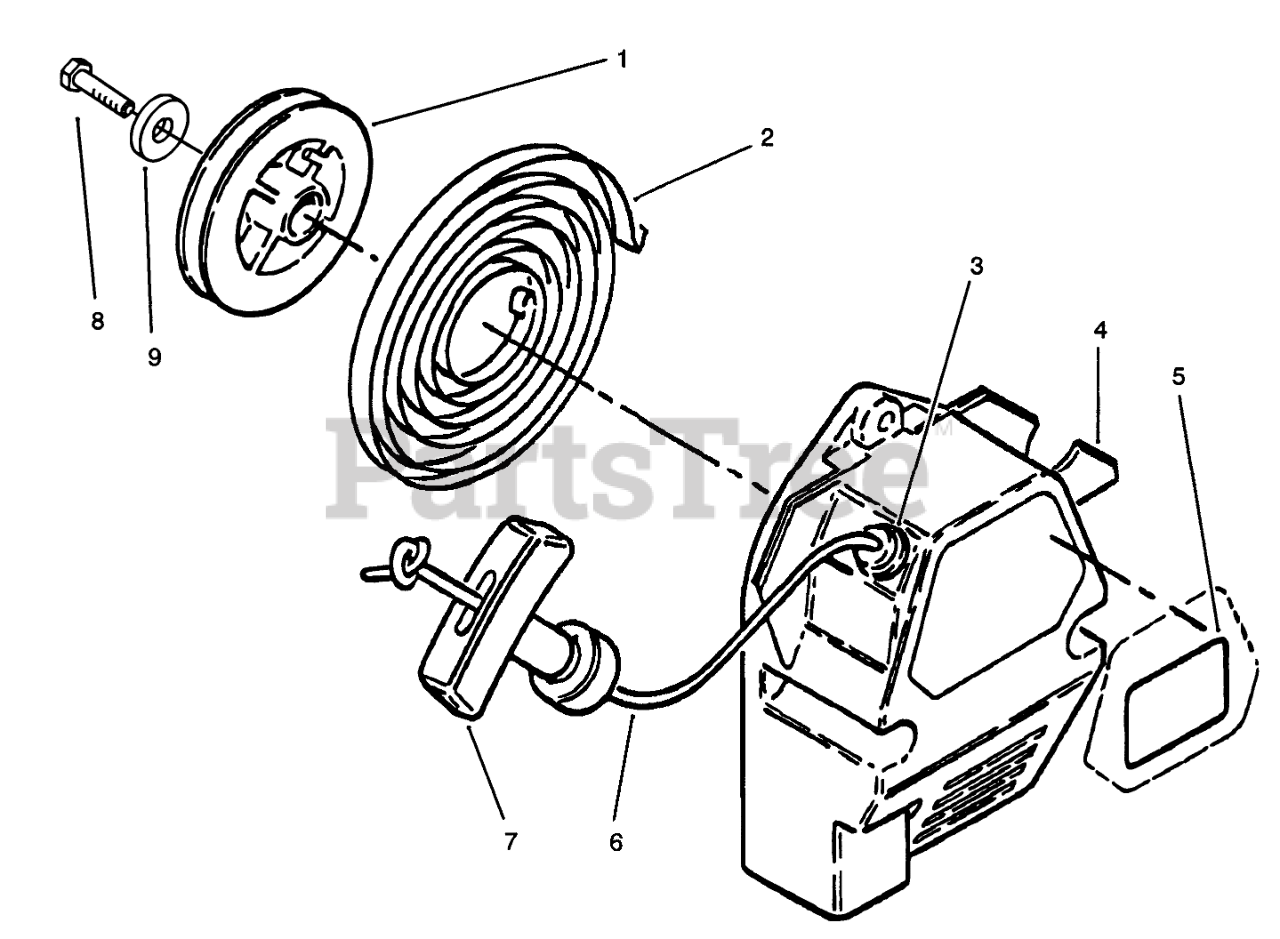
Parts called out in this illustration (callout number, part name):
2	SPRING
3	GUIDE
4	RECOIL CASE
5	Decal-Toro
6	Rope-Recoil
7	Knob-Starter
8	SCREW
9	Washer
